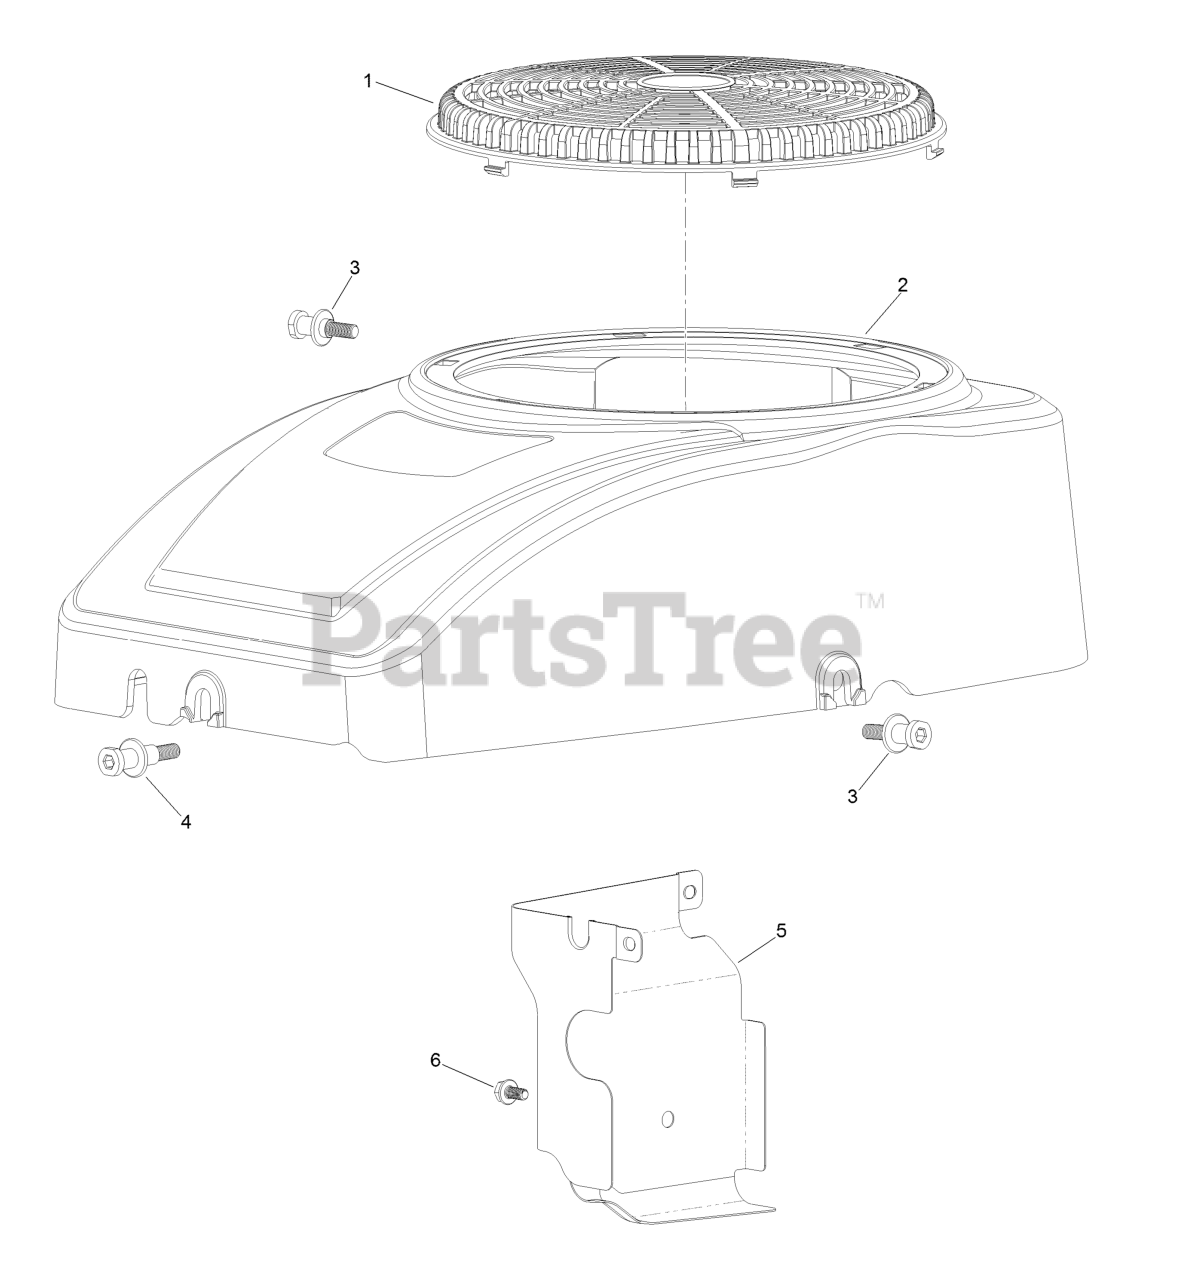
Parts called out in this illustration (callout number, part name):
1	SCREEN-STATIONARY
2	SHROUD-FAN
3	SCREW-SHOULDER, HH
4	SCREW-SHOULDER, HH
6	SCREW-HHF
